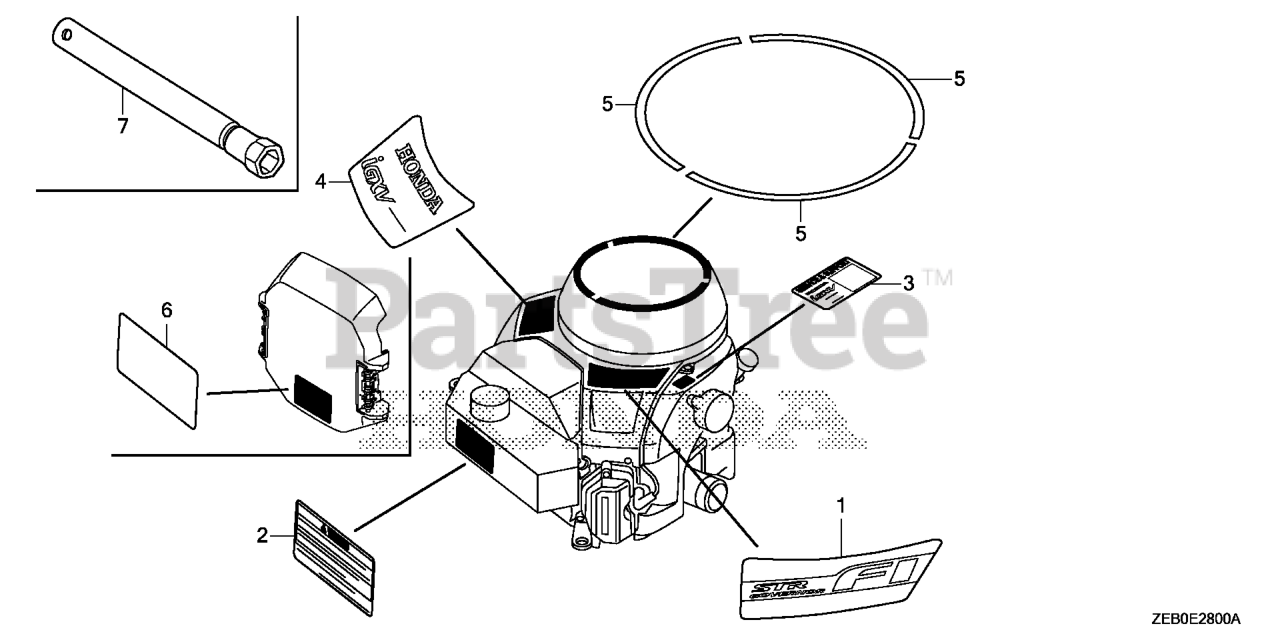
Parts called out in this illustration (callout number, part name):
2	MARK, OPERATOR CAUTION (ENGLISH)(MADE IN CHINA)
3	LABEL, QR CODE (SERVICE)
4	EMBLEM (GXV800)
